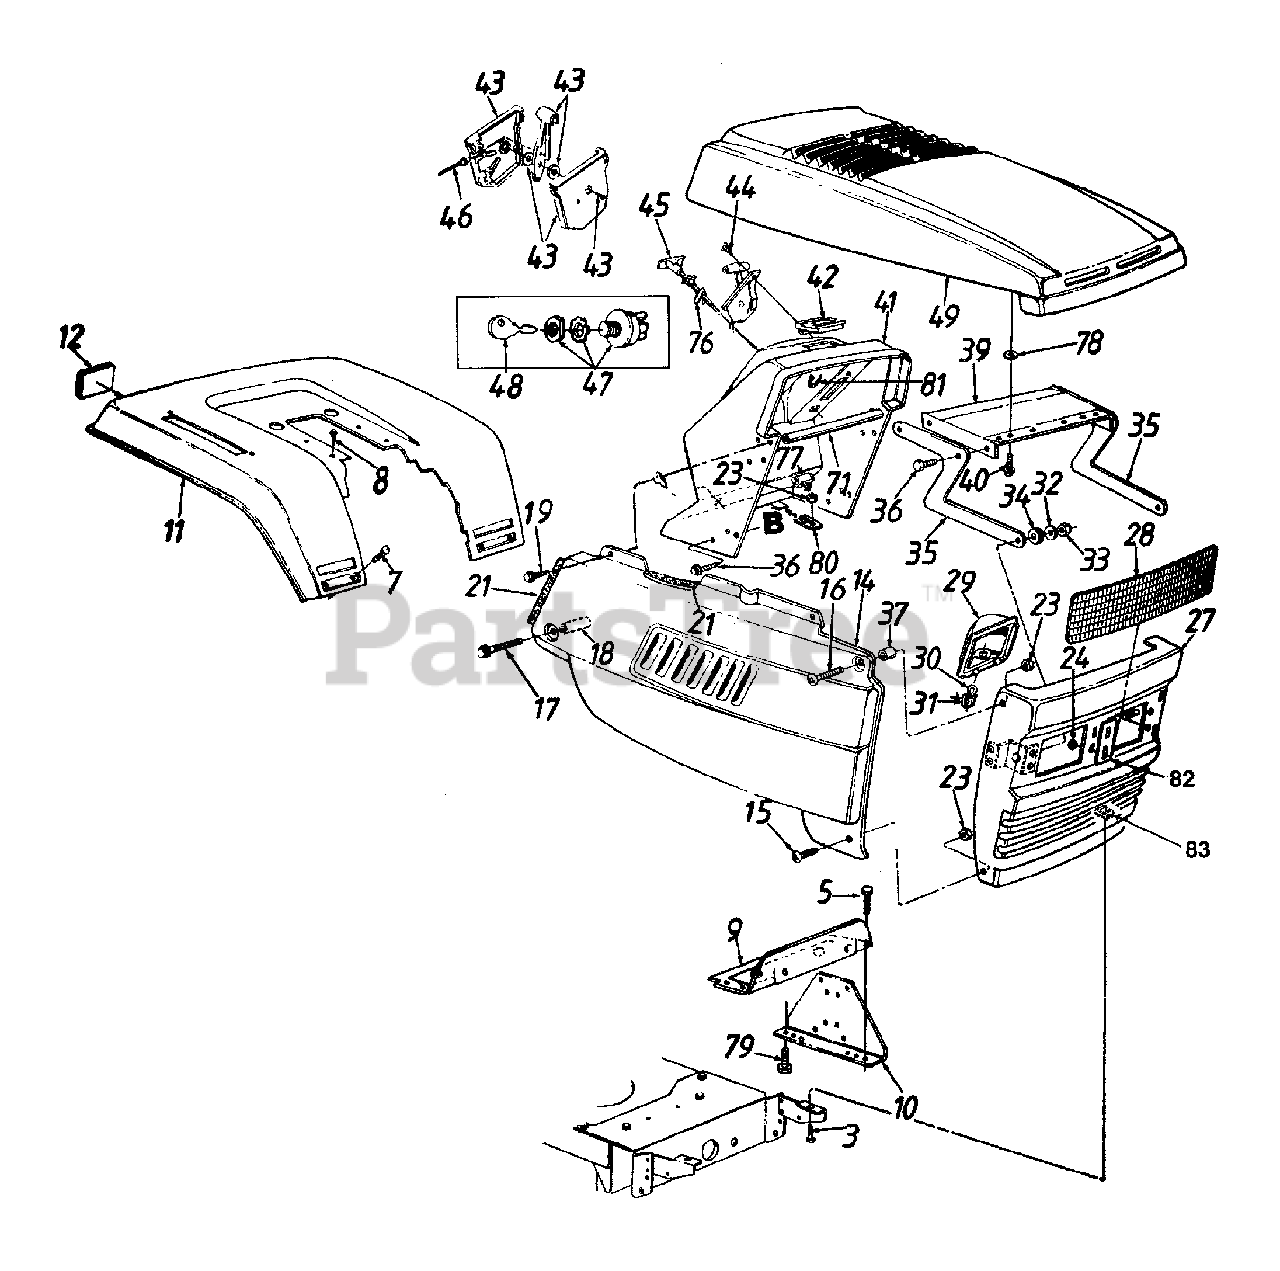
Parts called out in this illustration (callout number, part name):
3	Hex Bolt 5/16-18 x .1" Lg.
5	Hex Wash. Hd. Scr. 5/16" x .5" Lg.
7	Truss Mach. Scr.1/4-20 x .5" Lg.
8	Hex Wash. Hd. Tap Scr. 5/16 x .75" Lg.
16	Truss Mach. Scr. 1/4-20 x 1.0" Lg.
17	Hex Wash. TT-Tap Scr. 1/4-20 x 1.75" Lg.
18	Spacer .26" I.D. x 1.32"
19	Hex Rolling Tap Scr. 1/4-20 x.75" Lg.
21	Trim Strip-18" Lg.
23	Hex Sems Nut 1/4-20 Thd.
24	Speed Nut 5/16" Thd.
29	Headlamp Housing
30	Headlamp
31	Twist Lock Lamp Socket
32	Bell-Wash. .345" I.D. x .88"
33	Hex L-Nut 5/16-18 Thd.
34	Rubber Washer
37	Spacer .262" I.D. x .31"
41	Dash
42	Ammeter
43	Throttle Control Box Ass'y.
44	Mach. Scr. #10 x .44" Lg.
45	Choke Control 23" Lg.
46	Throttle Control Wire 18.5" Lg.
47	Ignition Switch
48	Ignition Key
49	Hood-Red
71	Grille Support Tube
76	Choke Retainer
77	Light Switch
78	Fl-Wash. .406" I.D. x .812" O.D.
79	Hex Bolt 1/4-20 x .88" Lg.
80	Dash Fastening Tab
81	Cable Tie
82	Chrome Label
83	U-Nut 5/16-18 Thd.
